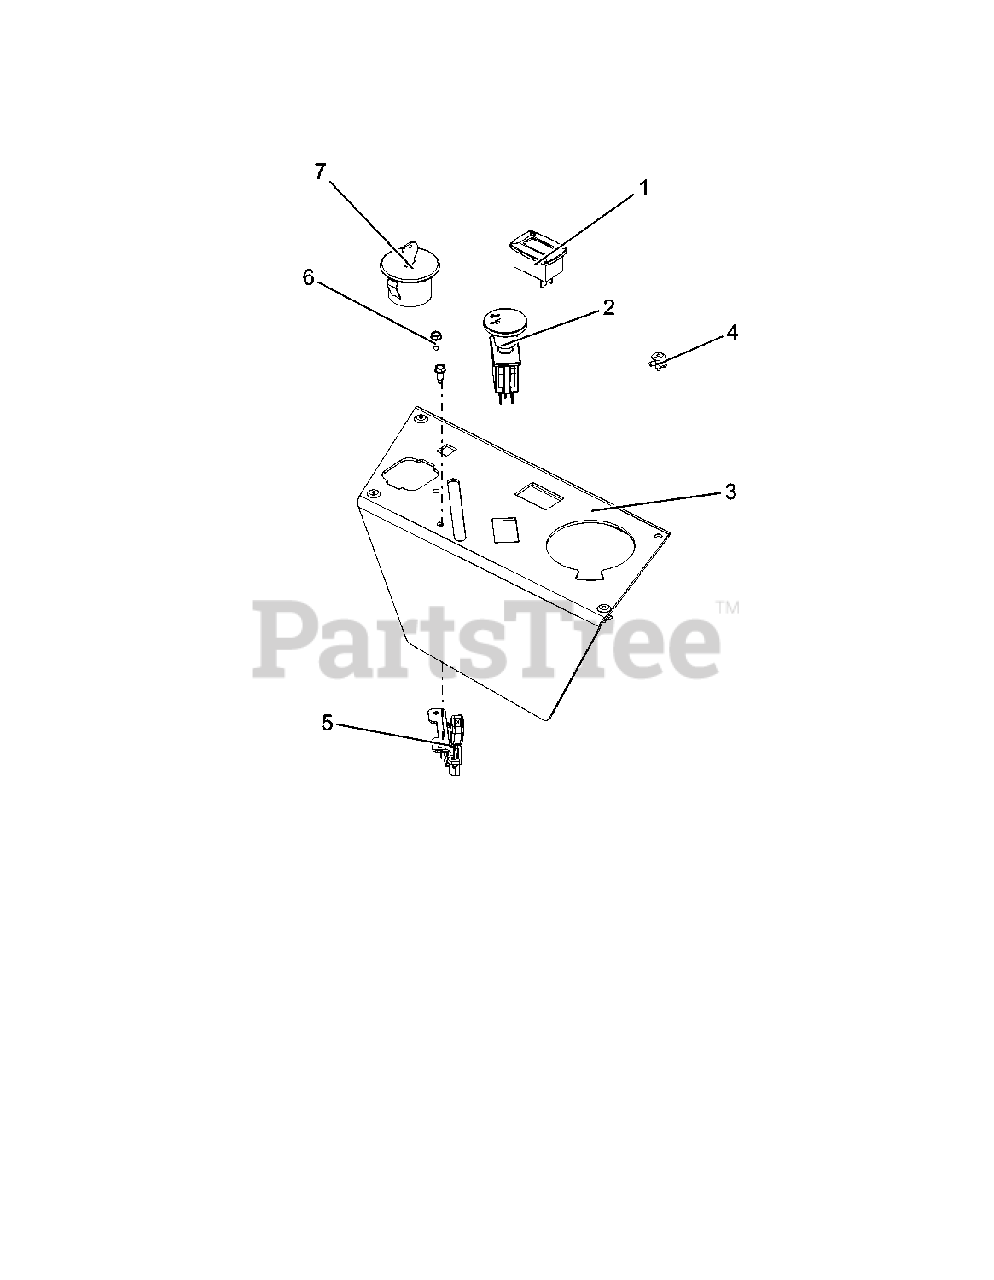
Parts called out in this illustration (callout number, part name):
1	METER, HOUR W/MAINTENANCE
2	SWITCH, CLUTCH YELLOW(W/GRAPHIC)
3	PANEL, CONTROL (RED)
4	RVT-POP .195 PLASTIC
5	CABLE, THROTTLE LH 90DEG 33"
6	SCR-TAP 10-24X.50 HWH TR YWZC
7	KEYSWITCH-IGNITION 3 POS
